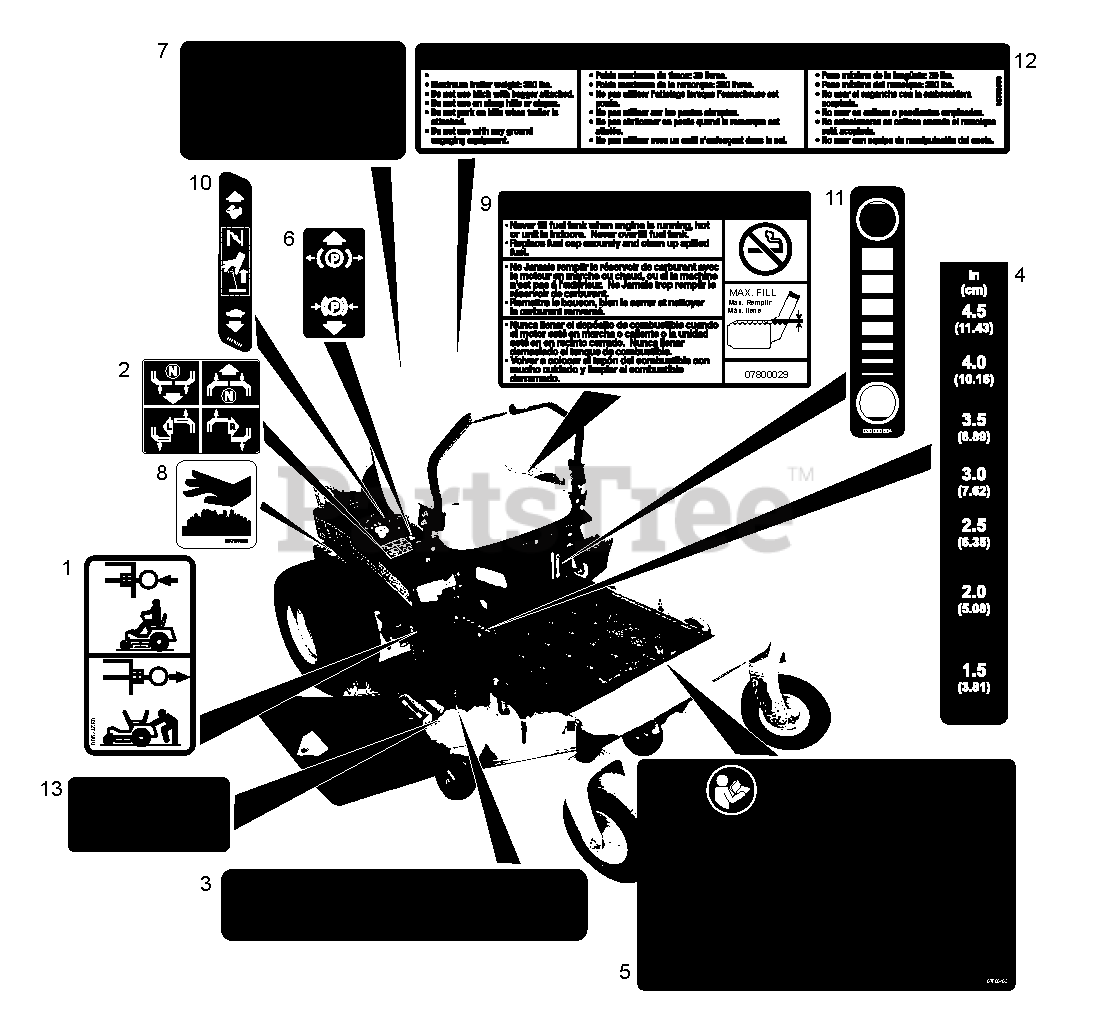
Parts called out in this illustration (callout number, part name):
1	Decal, Transmission Disconnect
2	Decal, Instructional Steering
3	Decal, Safety – Mower Deck
4	Decal, Cut Height
5	Decal, Safety – Main
6	Decal, Parking Brake Lever
7	Decal, Safety – Guarding
8	Decal, Hot Surface
9	Decal, Fuel Warning
10	Decal, Throttle/Choke Combo
11	Decal, Fuel Level
12	Decal, Trailer Hitch (915328)
13	Decal, Safety – Deck Guarding
